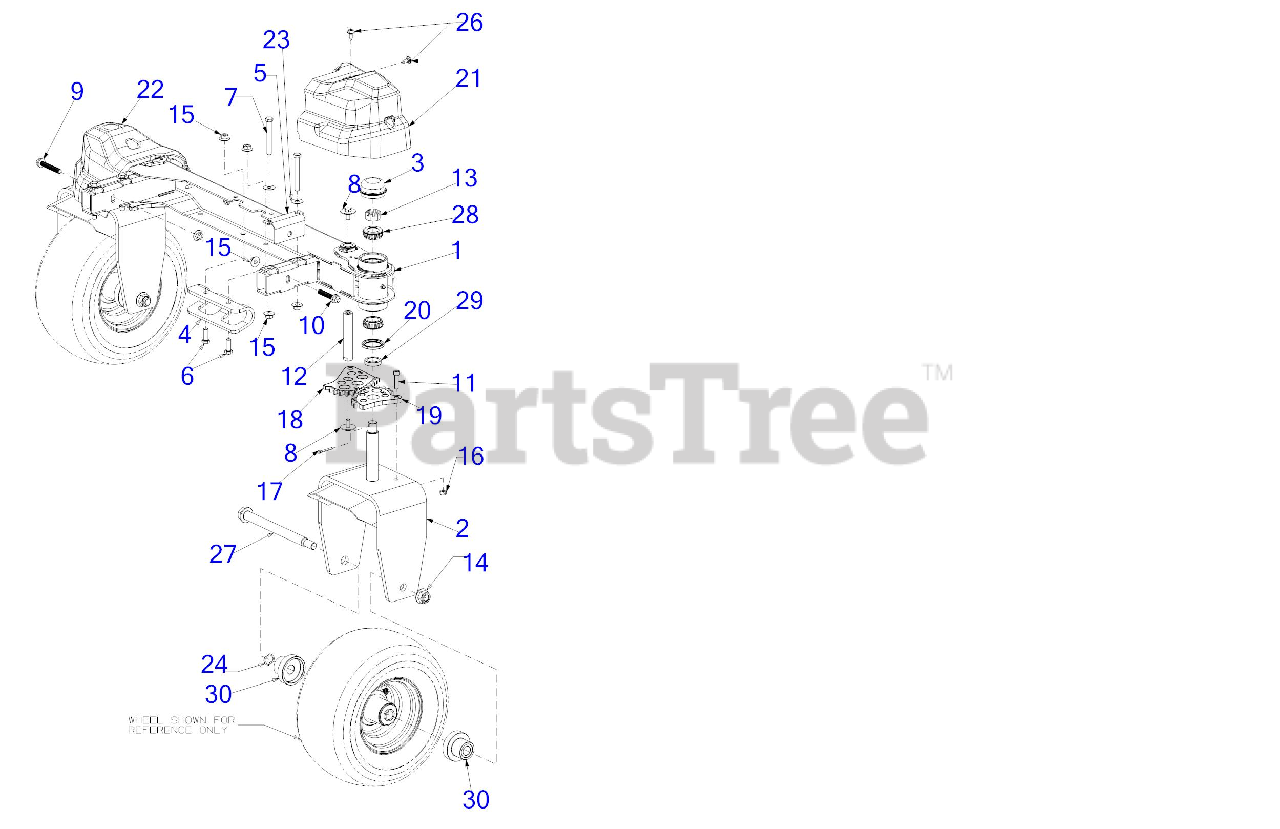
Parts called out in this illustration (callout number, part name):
1	FRONT AXLE
3	AXLE GREASE CAP
6	SCREW 3/8-16 x 1 GR5
7	SCREW 3/8-16 x 3 GR8
8	SCREW 5/16-18 X.75 GR5
9	SCREW 3/8-16 x 2.25 GR5
10	SCREW 3/8-16 x 2.00 GR5
11	SCREW 5/16-18X1.25
12	STEERING GEAR PIVOT SHAFT
13	HEX NUT CASTLE 3/4-16
14	FLANGE LOCK NUT
15	FLANGE LOCK NUT
16	HEX NUT
17	COTTER PIN-5/32 DIA
18	STEERING GEAR
19	STEERING SPUR GEAR 13T
21	AXLE COVER (RH)
22	AXLE COVER (LH)
23	FLAT WASHER
24	WAVE WASHER 1.115:0.750:.200
26	TORX SHOULDER SCREW 1/4-20
27	SHOULDER BOLT
28	ROLLER BEARING 47MM x 25MM x 15MM
30	HUB: 0.76 X 1.56 X 1.25
